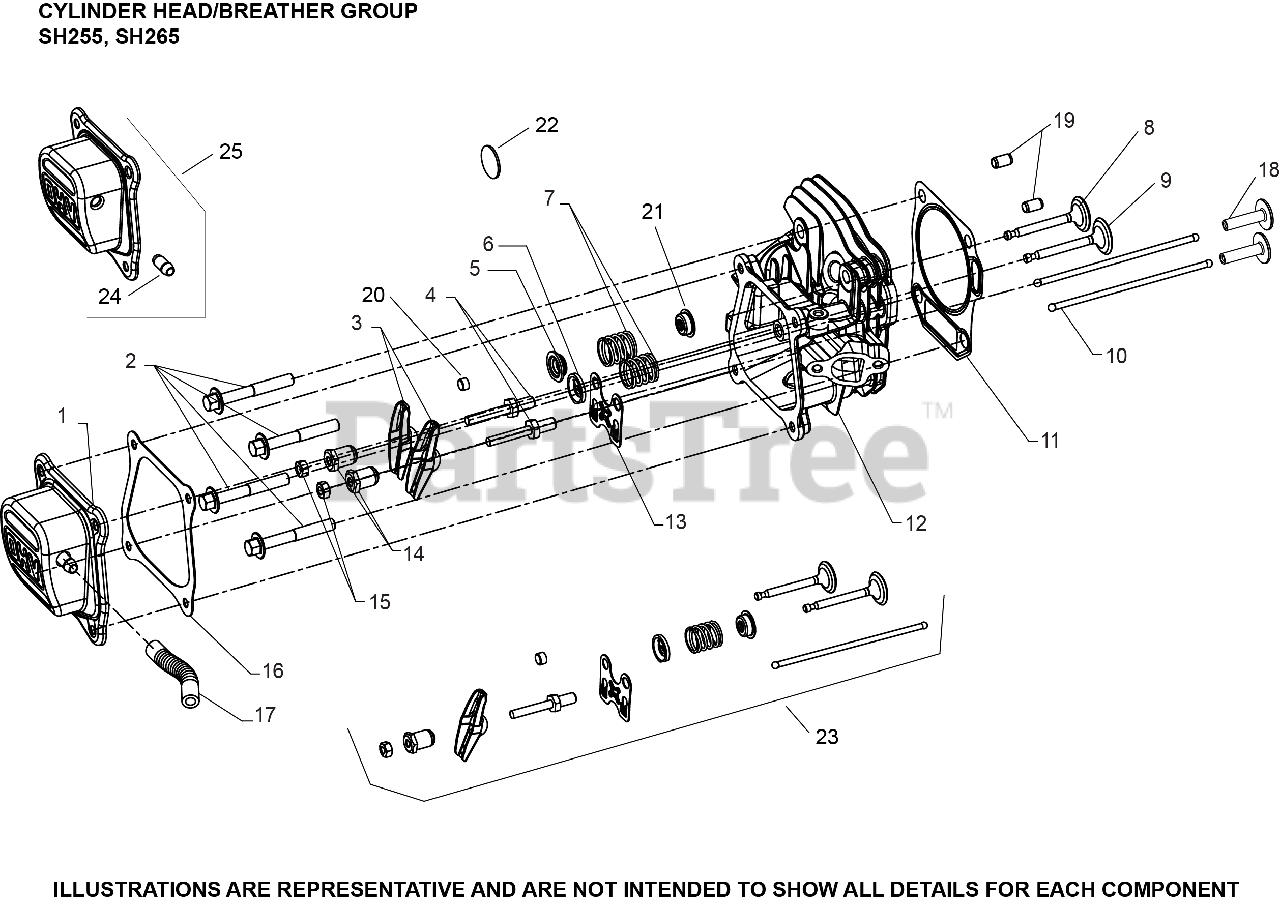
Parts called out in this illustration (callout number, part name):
1	COVER, VALVE ASSEMBLY
2	SCREW, HEX FLANGE CYL HEAD
3	ARM, ROCKER
4	STUD, ROCKER ARM - (#1407222S)
6	RETAINER, VALVE SPRING
7	SPRING, VALVE
8	VALVE, EXHAUST
9	VALVE, INTAKE
10	ROD, PUSH
11	KIT, HEAD GASKET
12	HEAD ASSEMBLY, CYLINDER
13	PLATE, PUSHROD GUIDE
14	PIVOT, ROCKER ARM
15	NUT, HEX JAM
21	SEAL, VALVE STEM
22	REED, BREATHER
23	KIT, VALVE TRAIN
1812314-S	TUBE, BREATHER
